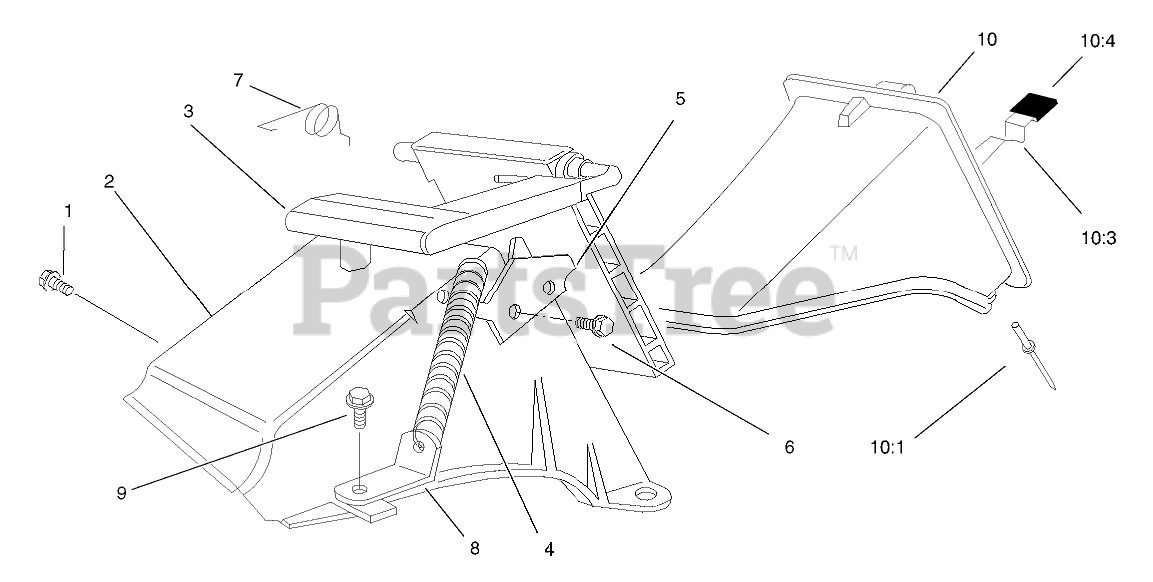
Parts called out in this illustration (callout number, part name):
1	SCREW AND WASHER ASM
2	TUNNEL-DISCHARGE
3	DISCHARGE DOOR ASM
4	SPRING-DOOR
5	LATCH-PLATE
6	SCREW-PLASTITE
7	RETAINER-DOOR
8	BRACKET-SPRING
9	SCREW-HWH
10	DISCHARGE PLUG ASM
10:1	RIVET-HEAD, FLAT
10:3	LATCH-PLUG, DISCHARGE
10:4	GRIP-LATCH
